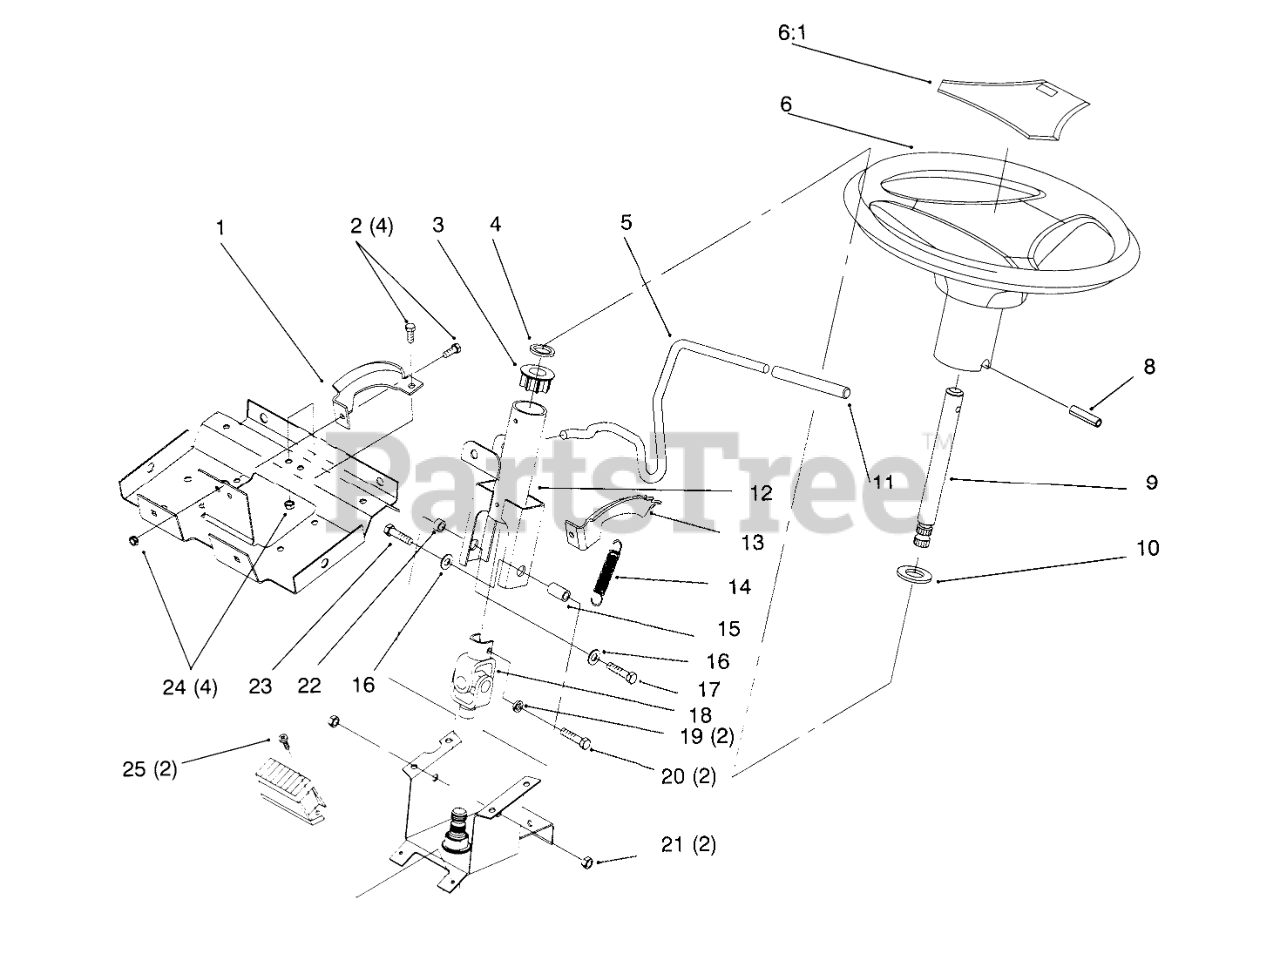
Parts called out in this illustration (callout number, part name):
1	BRACKET-SUPPORT, COLUMN
2	SCREW-HH
3	BUSHING-STEERING, UPPER
4	WASHER-BOWED
5	LEVER-TILT
6	Steering Wheel (Only On: 72042,72043,72062)
6	Steering Wheel (Only On: 72063,72103)
6:1	Cover-Steering Wheel (Only On: 72063,72103)
6:2	Cover-Steering Wheel (Only On: 72043,72062)
8	PIN-ROLL
9	SHORT UPPER STRG SHAFT
10	WASHER-FLAT
11	CAP-ROD, TILT
12	Column
13	BRACKET-DETENT
14	SPRING-EXTENSION
15	SPACER-YOKE
16	WASHER-PLAIN
17	SCREW-HH
18	U-JOINT, STEERING
19	WASHER-LOCK
20	SCREW-CAP, HH
21	NUT-LOCK, NI
22	SPACER-YOKE, RIGHT
23	SCREW-HH
24	NUT-HEX
25	SCREW-PPHTF
